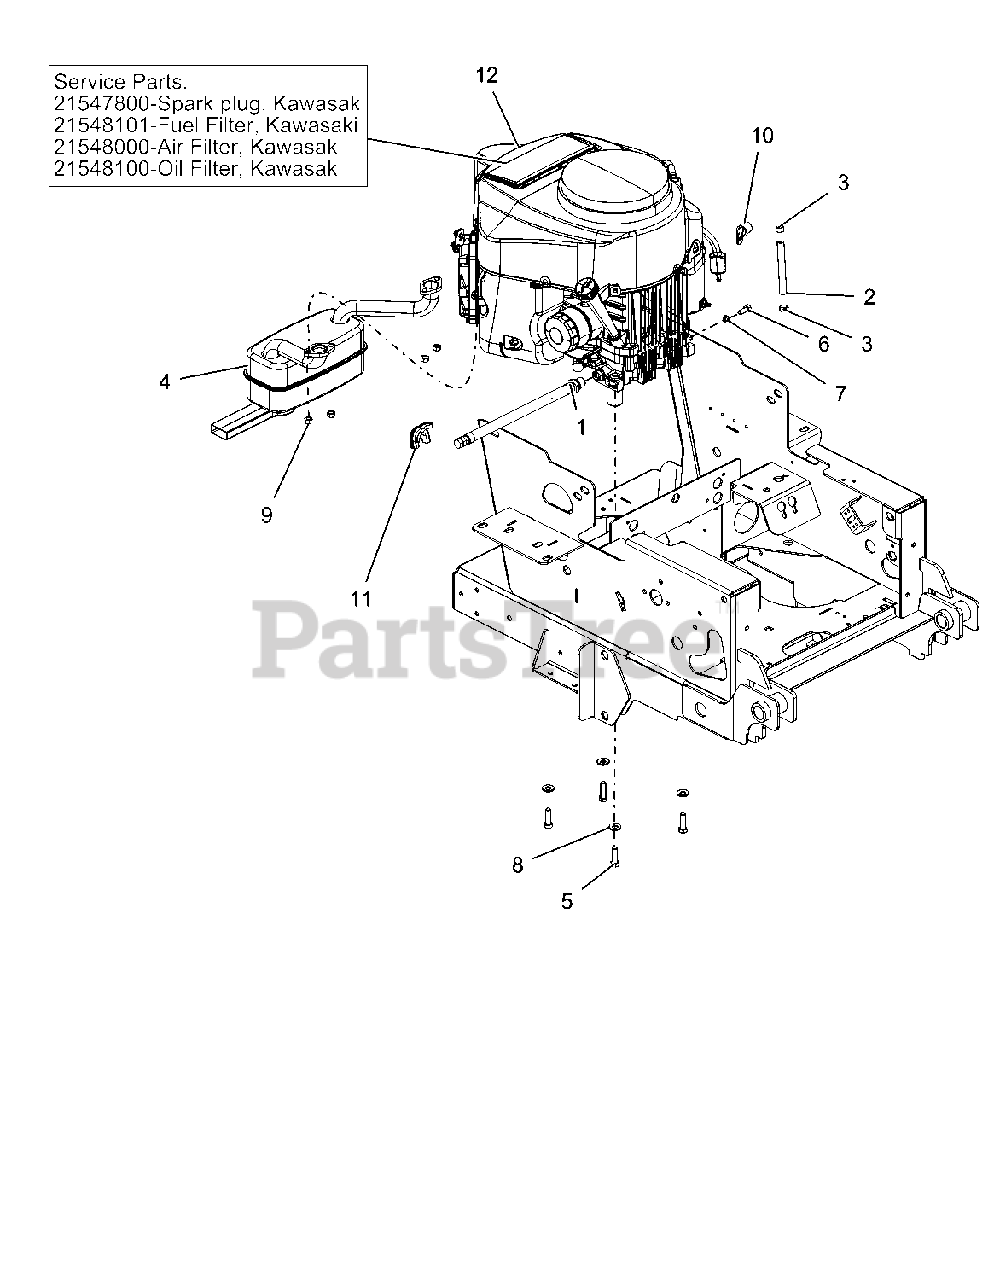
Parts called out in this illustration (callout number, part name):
1	HOSE, OIL DRAIN
2	.25 LOW-PERM GAS HOSE 4.00" LG - TANK TO ENGINE
3	CLAMP, FUEL LINE
4	MUFFLER, KAWASAKI
5	BLT-HEX .38-16X1.25 GR5 YWZC NYTORQ
6	@BLT-HEX M8-1.25X20 YWZC
7	WSHR-LK .31X.078 REG YWZC
8	WSHR, 3/8" SPRING DISC
9	NUT-LK-TOP M8-1.25 YWZC
10	CLAMP, CUSHIONED STEEL .75
11	PROTECTOR, OIL DRAIN HOSE
12	ENGINE, KAWASAKI FR SERIES
12	SPARK PLUG
12	FUEL FILTER
12	AIR FILTER
12	OIL FILTER
